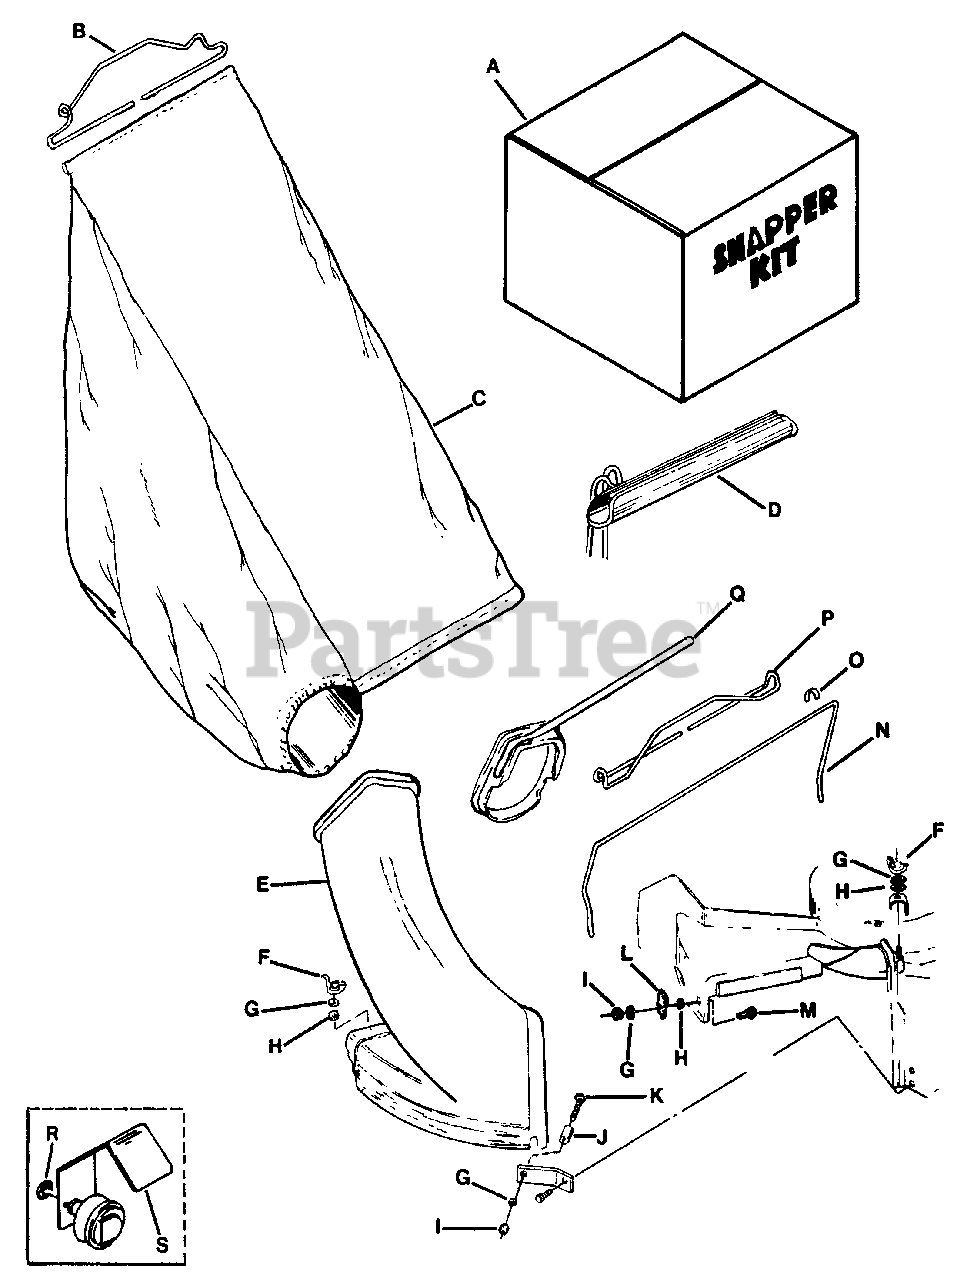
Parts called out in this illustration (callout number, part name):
A	KIT, V18 Grass Catcher
B	WIRE, Rear
C	BAG, Grass
D	ASSEMBLY, Slider
E	ADAPTER, V18 Bag
F	NUT, 5/16-18 Wing Lock
G	WASHER, 5/16 Split Lock
H	WASHER, 5/16 SAE Flat
I	NUT, 5/16-18 Hex
K	SCREW, 5/16-18 x 1-1/8" Flat Head Countersunk Machine
L	BRACKET, Guide
M	BOLT, 5/16-18 x 1" Short Neck Carriage, Grade 5
N	BAR, Roll
O	RING, Nylon
P	WIRE, Front
Q	CONNECTOR, Bag
R	WASHER, 13/16" Internal Tooth Lock
S	SHIELD, Exhaust Heat (Briggs engine)
